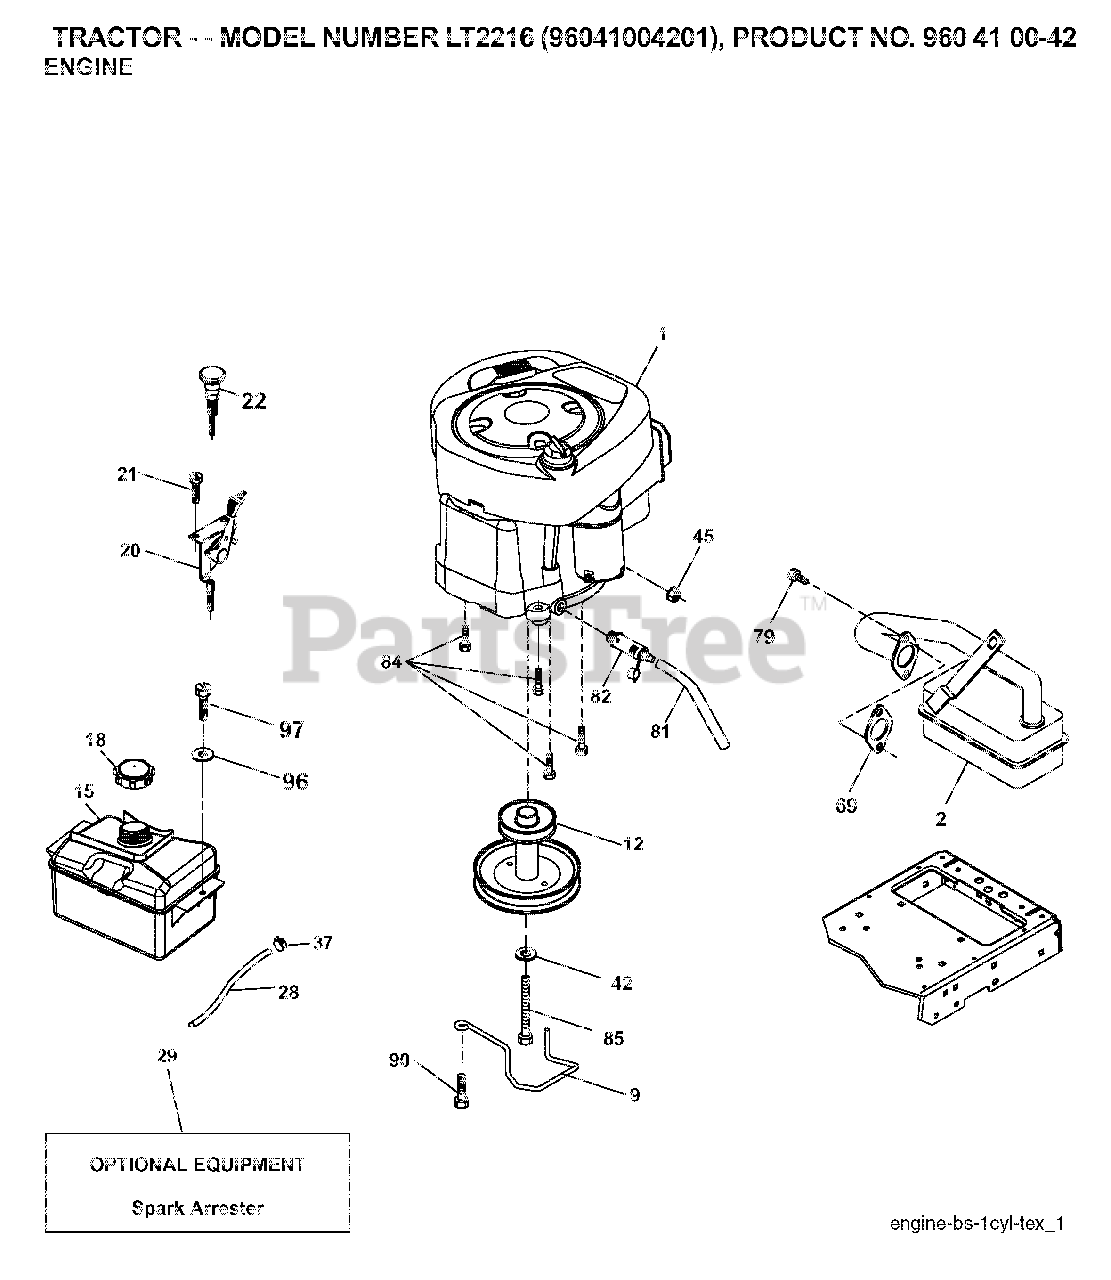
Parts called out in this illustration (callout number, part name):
9	KEEPER.BELT.ENGINE.3.25
12	PULLEY ENGINE
15	TANK FUEL FRT 1.5 GAL
18	FUEL CAP
20	CONTROL.TH/CK.C.
21	SCREW
28	LINE.FUEL.20
29	ARRESTER SPARK (OPTIONAL)
37	HOSE CLAMP
42	LOCKWASHER
45	NUT
69	REPL BY 532 27 22-93
79	SCREW.SOCKET HD.5/16-1
81	TUBE, DRAIN OIL ASM.
82	PLUG DRAIN OIL EASY
84	SCREW.3/8-16
85	BOLT HEX 7/16-20X4-1/4"
90	SCREW 3/8-16X1
97	SCREW HEXWSHR 1/4-20X3/4
